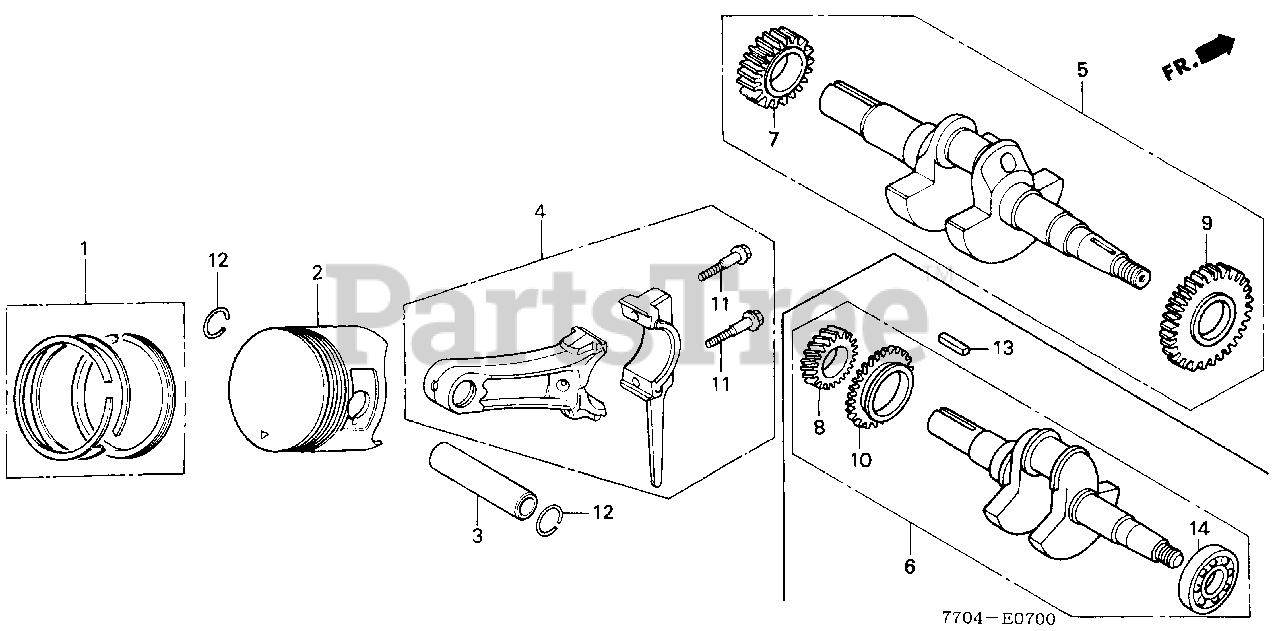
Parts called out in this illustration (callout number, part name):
1	RING SET, PISTON (STD) (TEIKOKU)
1	RING SET, PISTON (STD) (NIPPON)
1	RING SET, PISTON (0.25) (TEIKOKU)
1	RING SET, PISTON (0.25) (NIPPON)
1	RING SET, PISTON (0.50) (TEIKOKU)
1	RING SET, PISTON (0.50) (NIPPON)
1	RING SET, PISTON (0.75) (TEIKOKU)
1	RING SET, PISTON (0.75) (NIPPON)
2	PISTON (STD)
2	PISTON (0.25)
2	PISTON (0.50)
2	PISTON (0.75)
3	PIN, PISTON
4	ROD ASSY., CONNECTING (STD)
4	ROD ASSY., CONNECTING (0.25 LOWER SIZE)
6	CRANKSHAFT
11	BOLT, CONNECTING ROD
12	CLIP, PISTON PIN (18MM)
13	KEY (7X7X33) (OVER SIZE) (YELLOW)
14	BEARING, RADIAL BALL (6206)
